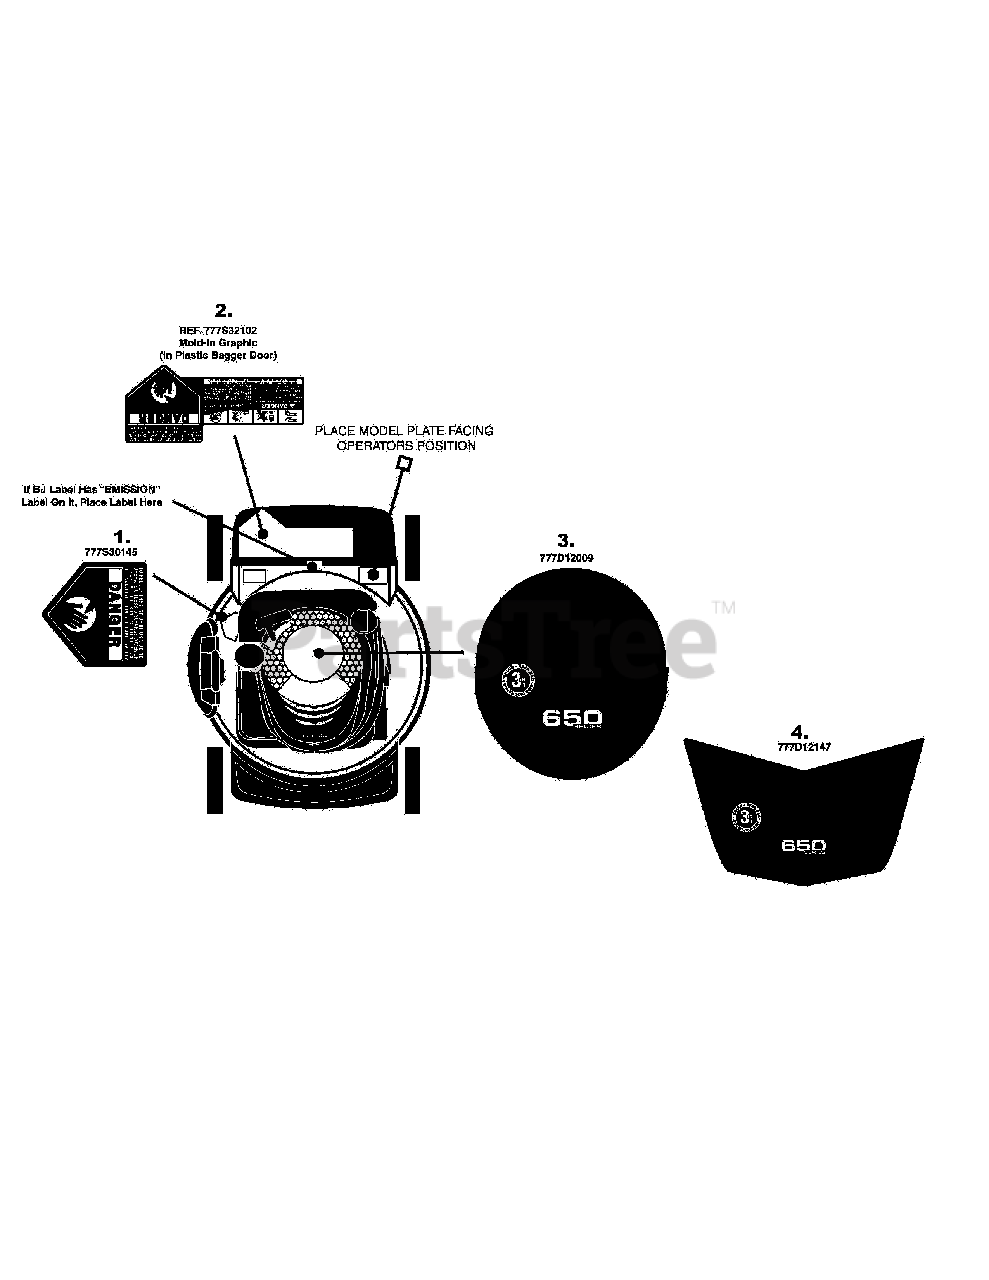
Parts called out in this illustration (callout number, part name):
1	LABEL
2	LABEL
3	LABEL-MOWER SHROUD MTD GOLD 21"
4	LABEL-MOWER SHROUD MTD GOLD 21"
